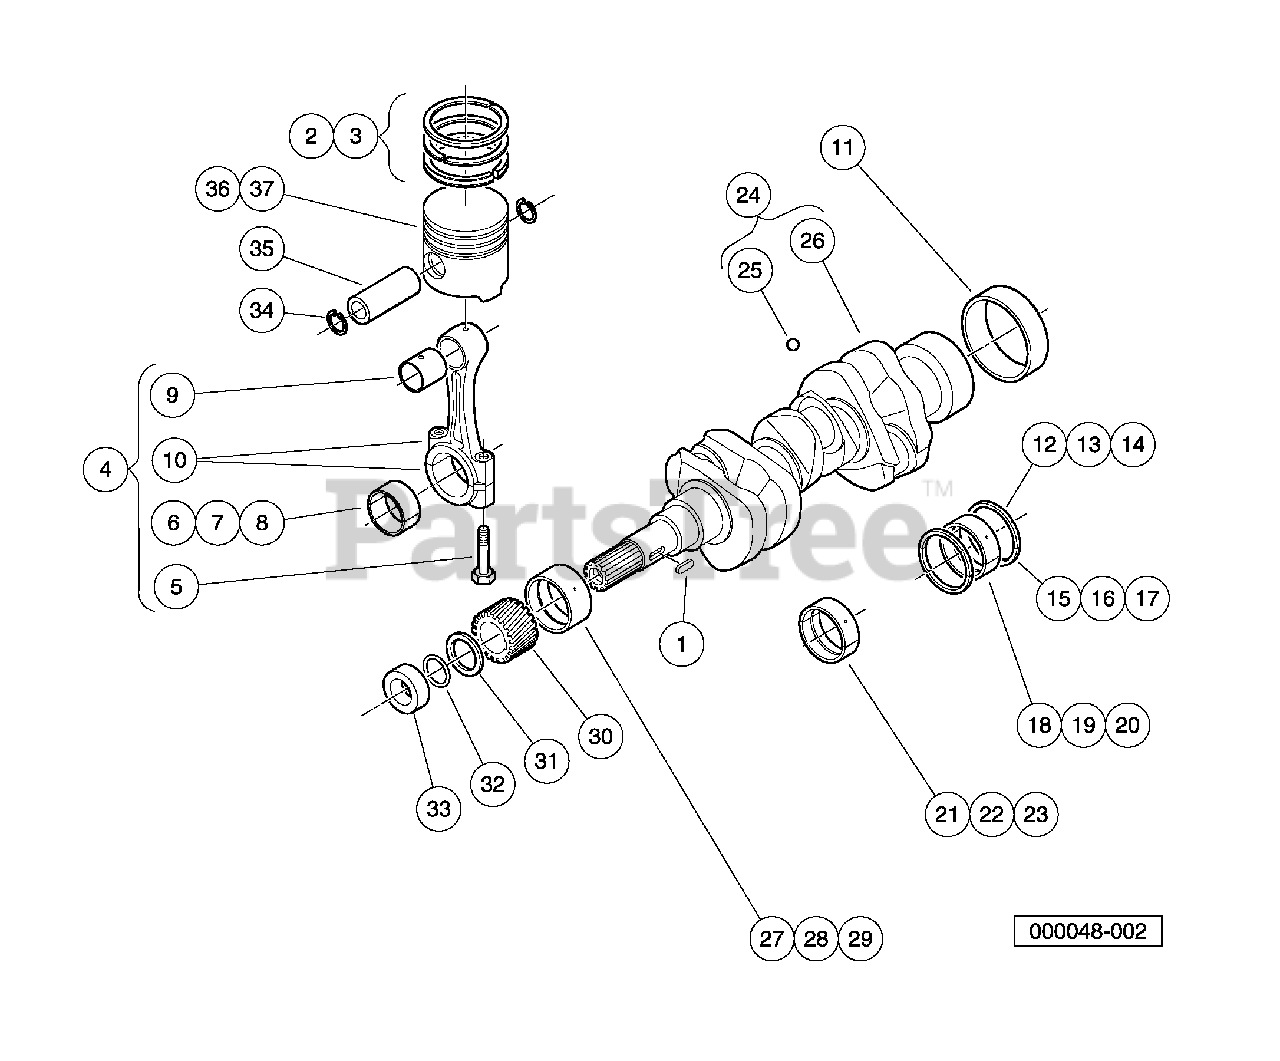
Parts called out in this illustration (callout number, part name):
1	Key, Feather, Short Camshaft
2	Assy Piston Ring, D722 Std
3	Assy Piston Ring, D722 +.025
4	Assy, Connecting Rod
5	Bolt, Connecting Rod
6	Metal, Crank, Rod, D722, Std
7	Metal, Crank, Rod, D722, .020
8	Metal, Crank, Rod, D722, .040
9	Bushing, Piston Pin, D722
10	Rod, Connecting
11	Sleeve, Crankshaft
12	Metal,crank, O Side, Std
13	Metal,crank, O Side, +.020
14	Metal,crank, O Side, +.040
15	Metal,crank, I Side, Std
16	Metal,crank, I Side, +.020
17	Metal,crank, I Side, +.040
18	Metal, Crank, Main, Rear Std
19	Metal, Crank, Main, Rear -.020
20	Metal, Crank, Main, Rear -.040
21	Metal, Crank, Main, Mid Std
22	Metal, Crank, Main, Mid +.020
23	Metal, Crank, Main, Mid +.040
24	Crankshaft
25	Ball, Crankshaft
26	Crankshaft
27	Metal, Crank, D722, Frnt, Std
28	Metal, Crank, 722, Frnt, -.020
29	Metal, Crank, 722, Frnt, -.040
30	Gear, Crank
31	Slinger, Oil
32	O Ring, 23 X 26
33	Collar, Crankshaft
34	Circlip, Piston Pin
35	Pin, Piston
36	Piston, D722, Std
37	Piston, D722, +0.25
